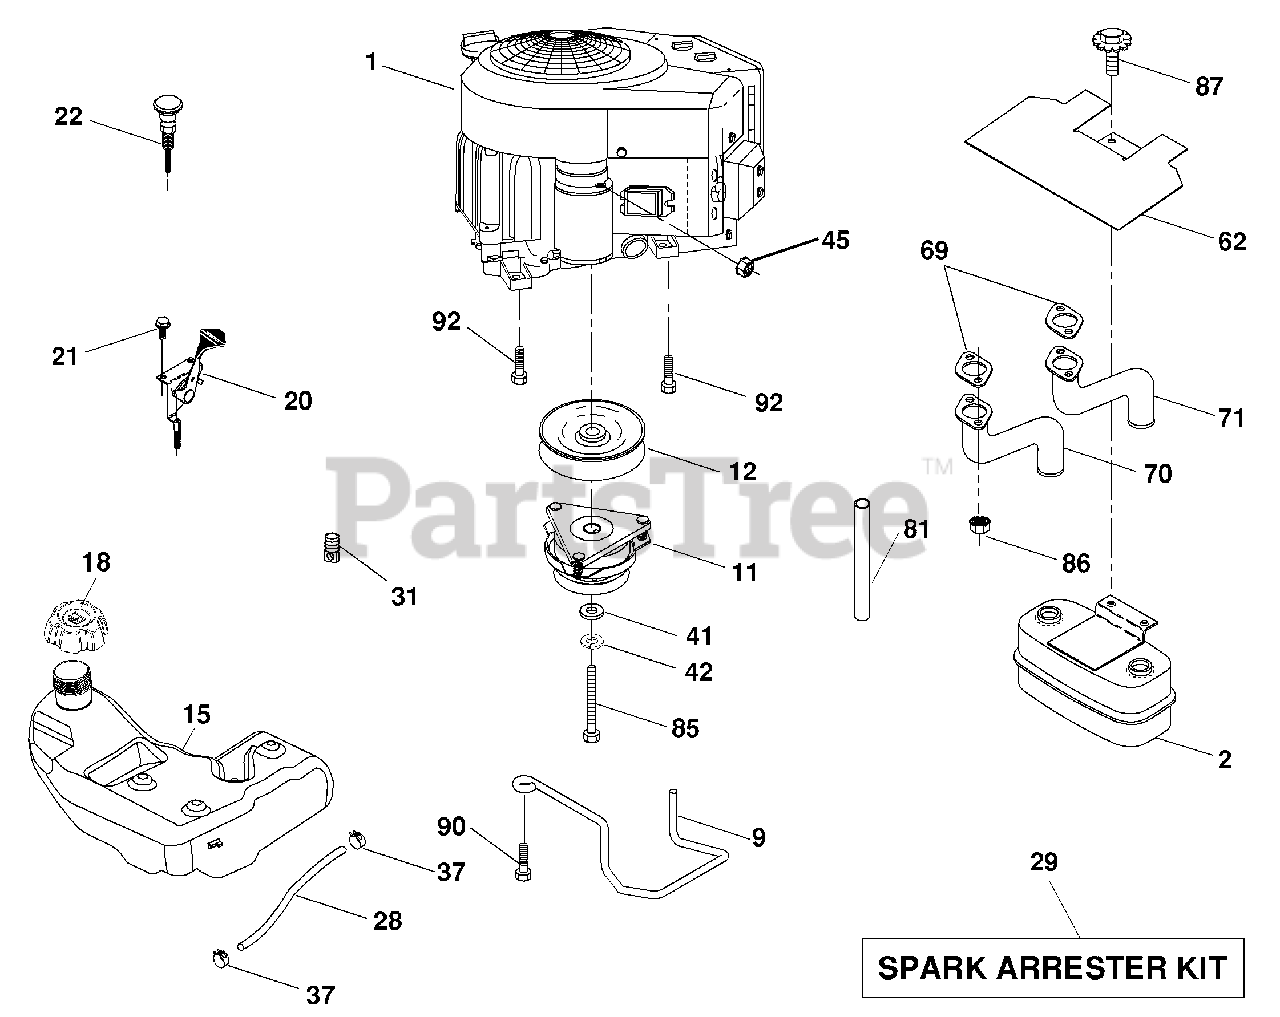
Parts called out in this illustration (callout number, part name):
9	Keeper Belt Engine
11	Clutch Electric
12	Pulley Engine
15	Tank Fuel 4.0
18	Cap Asm
20	Control Throttle
21	Screw 10 x 3/4 Single Lead Hex
22	Control Choke
28	Fuel Line
29	Spark Arrester Kit
31	Clip Push-In
37	Clamp Hose
41	Washer 1-1/2 OD x 15/32 ID x .250
42	Washer Lock 7/16
45	Nut Keps Hex 1/4-20 unc
62	Shield Heat Muffler
70	Tube Exhaust LH
71	Tube Exhaust RH
81	Tube Drain Oil Easy
85	Bolt Hex 7/16-20 x 4 x Gr. 5-1.5
86	Nut Hex Flange Toplock M8-1.2
87	Bolt 5/16-18 unc x 1 w/Sems
90	Screw 3/8-16 x 1
92	Screw 3/8-16 x 1
